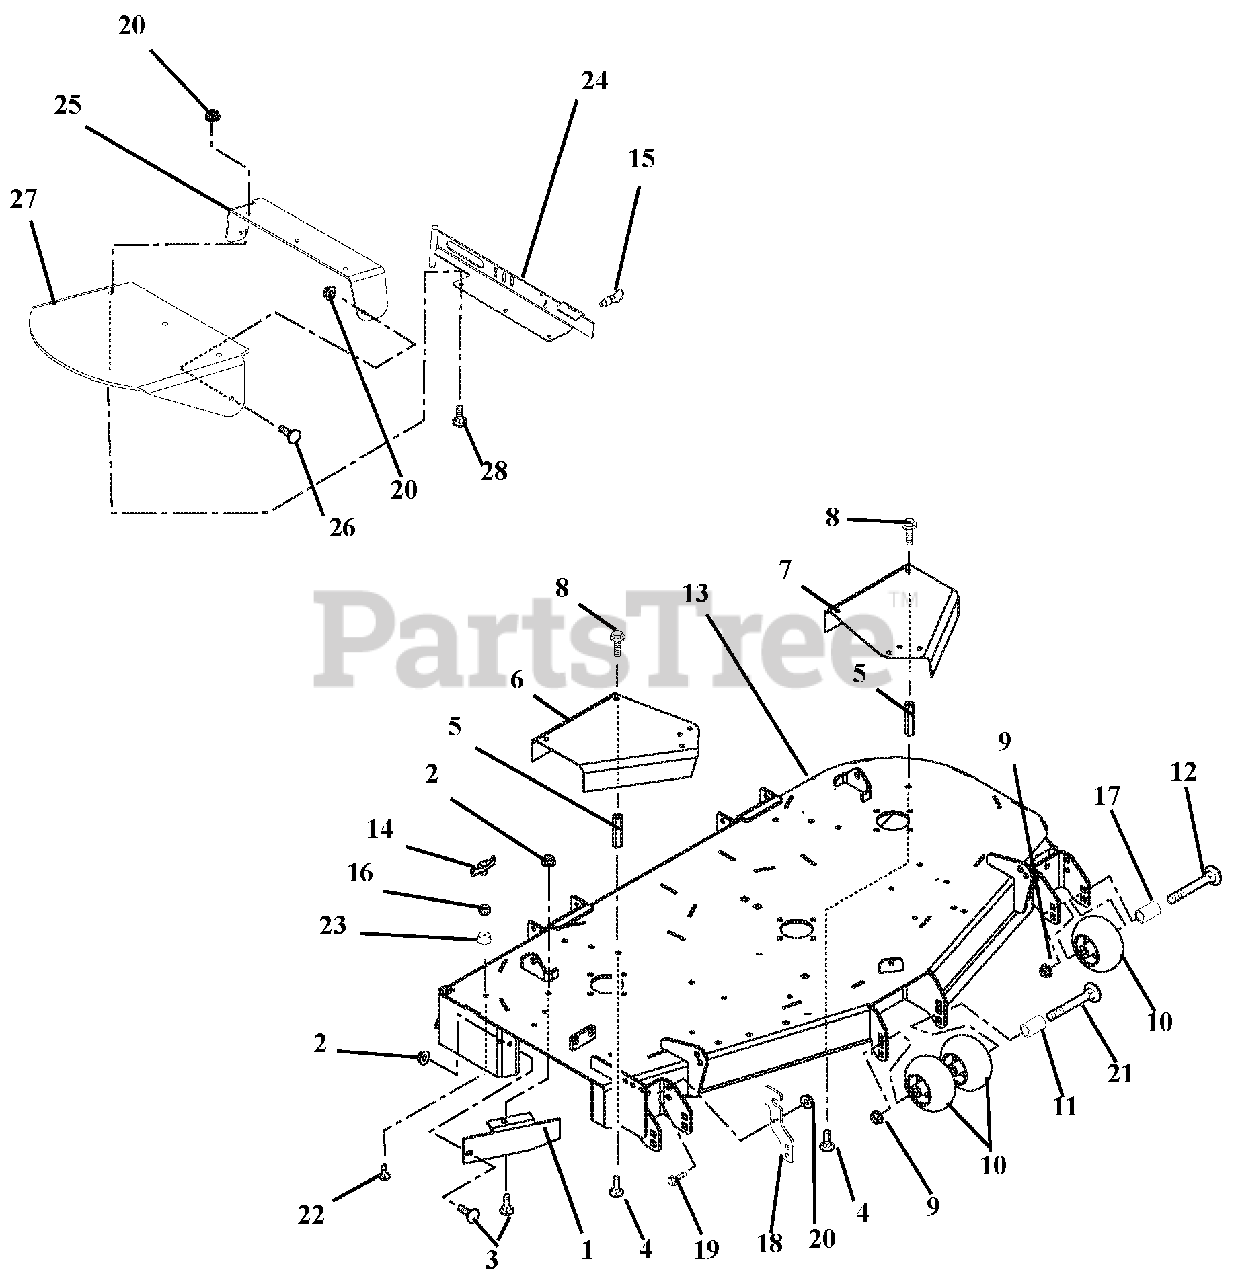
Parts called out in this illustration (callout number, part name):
1	52-in. Rear Discharge Baffle (992125)
2	Nut, .31-18 Nyloc Flange
3	Bolt, Round Head Square Neck .31-18 x 1.00 Grade 5
4	Bolt, Round Head Square Neck .31-18 x .75 Loctite with Epoxy Patch
5	Nut, Coupling .31-18 x 3.00
6	52-in. Right Hand Spindle Guard (992125)(Serial Number 000699 and Below)
7	52-in. Left Hand Spindle Guard (992125)
8	Bolt, SEMS .31-18 x .62
9	Nut .50-13 Nyloc Flange
10	Anti-Scalp Wheel
12	Bolt-Round Head Square Neck .50-13 x 5.00
13	52-in. Mower Deck (992125)
14	Knob, Wing .312-18
15	Pin, Pull Plunger .50-13 Thread x .310
16	Nut, Locking Center .31-18
17	Spacer, .510 x .625 x 3.35
18	Chute, Storage Bracket
19	Bolt, Hex .38-16 x 1.00
20	Nut, .38-16 Nyloc Flange
21	Bolt, Round Head Square Neck .50-13 x 8.50
22	Bolt, Round Head Square Neck .31-18 x 1.50
23	Bumper, Recessed 1.50 x .63 , .31 Thru Hole
24	52-inch and 60-inch Discarch Chute Mounting Weldment (992121, 125, 136, 137))
25	Rubber Discharge Chute Support
26	Bolt, Round Head Square Neck .38-16 x 1.00 Grade 5
27	Chute, Rubber Discharge
28	Bolt, Round Head Square Neck .38-16 x 1.25 Grade 5
